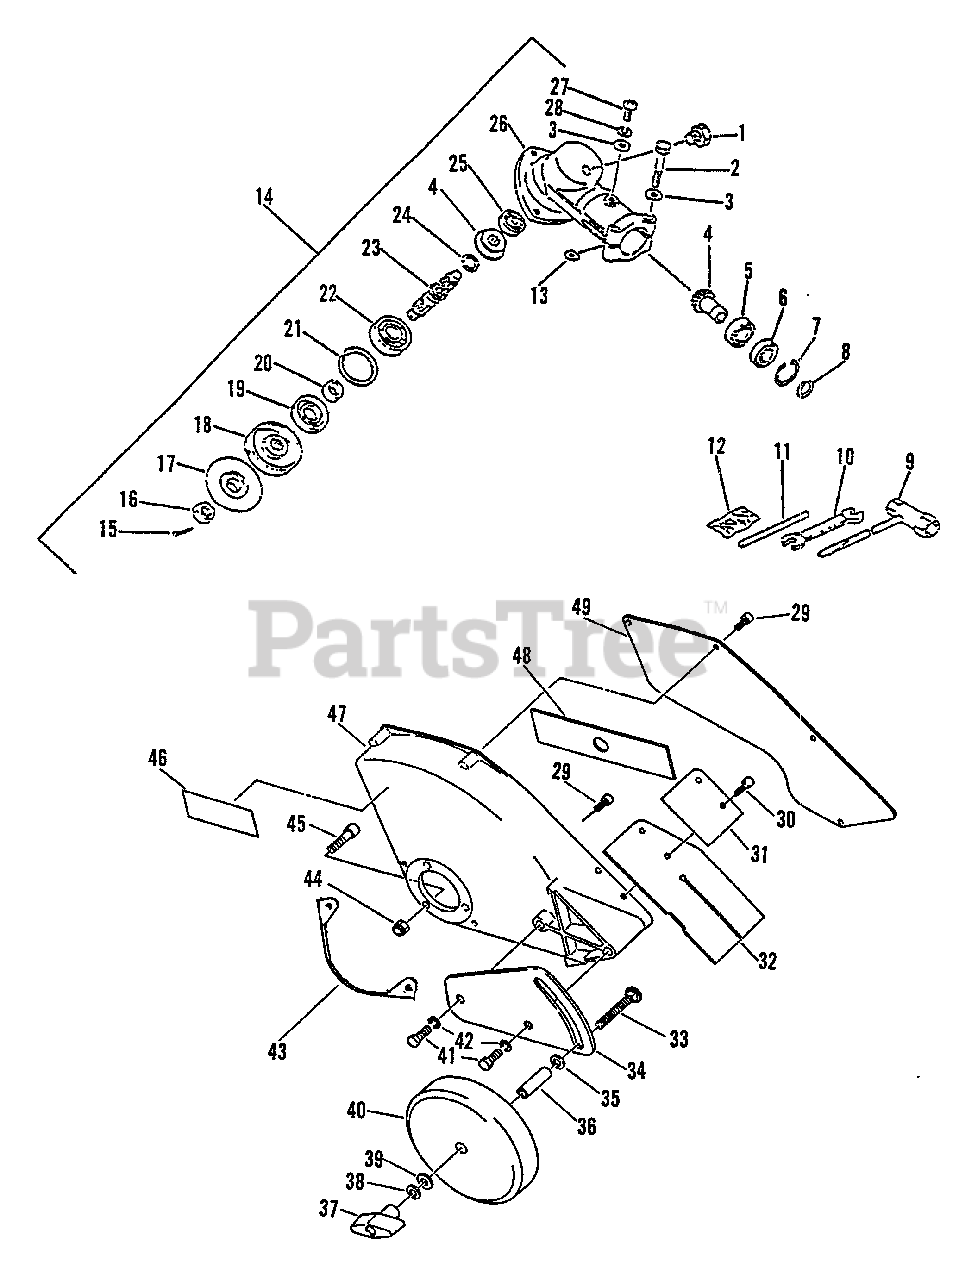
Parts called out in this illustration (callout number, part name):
1	BOLT - 8X8
2	BOLT - 5X35
3	WASHER - 5
4	GEAR SET - BEVEL
5	BEARING, BALL - 6900
6	BEARING, BALL - 6900Z
7	RING, RETAINING - 22
8	RING, RETAINING - 12
9	T-WRENCH - 17X19mm
10	SPANNER - 8X10mm
11	LOCKING TOOL
12	PIN, SPLIT - 2X22
14	GEAR CASE ASSY
15	PIN, SPLIT - 2X22
16	NUT - 10 -- LEFT HAND
17	ADAPTOR, BLADE - LOWER
18	ADAPTOR, BLADE - UPPER
19	SEAL, OIL
21	RING, RETAINING - 32
22	BEARING, BALL - 6201
23	GEAR - SHAFT
24	RING, RETAINING - 10
25	BEARING, BALL - 609
26	CASE, GEAR
27	SCREW - 5X10
28	LOCKWASHER - 5
29	SCREW - 4X10
30	SCREW - 4X14
31	FLAP, DEBRIS
32	FLAP, DEBRIS
33	BOLT - CARRIAGE
34	BRACKET, WHEEL
35	WASHER - 10
36	COLLAR - 12
37	WINGNUT - 5/16-18
38	LOCKWASHER - 8
39	WASHER - 8
40	WHEEL - 6X1.5
41	BOLT - 8X14
42	LOCKWASHER - 8
43	SHIELD, DEBRIS
45	SCREW - 5X22
46	LABEL - CAUTION
47	NEW BLADE SHIELD
48	BLADE, EDGER
49	COVER, SHIELD
